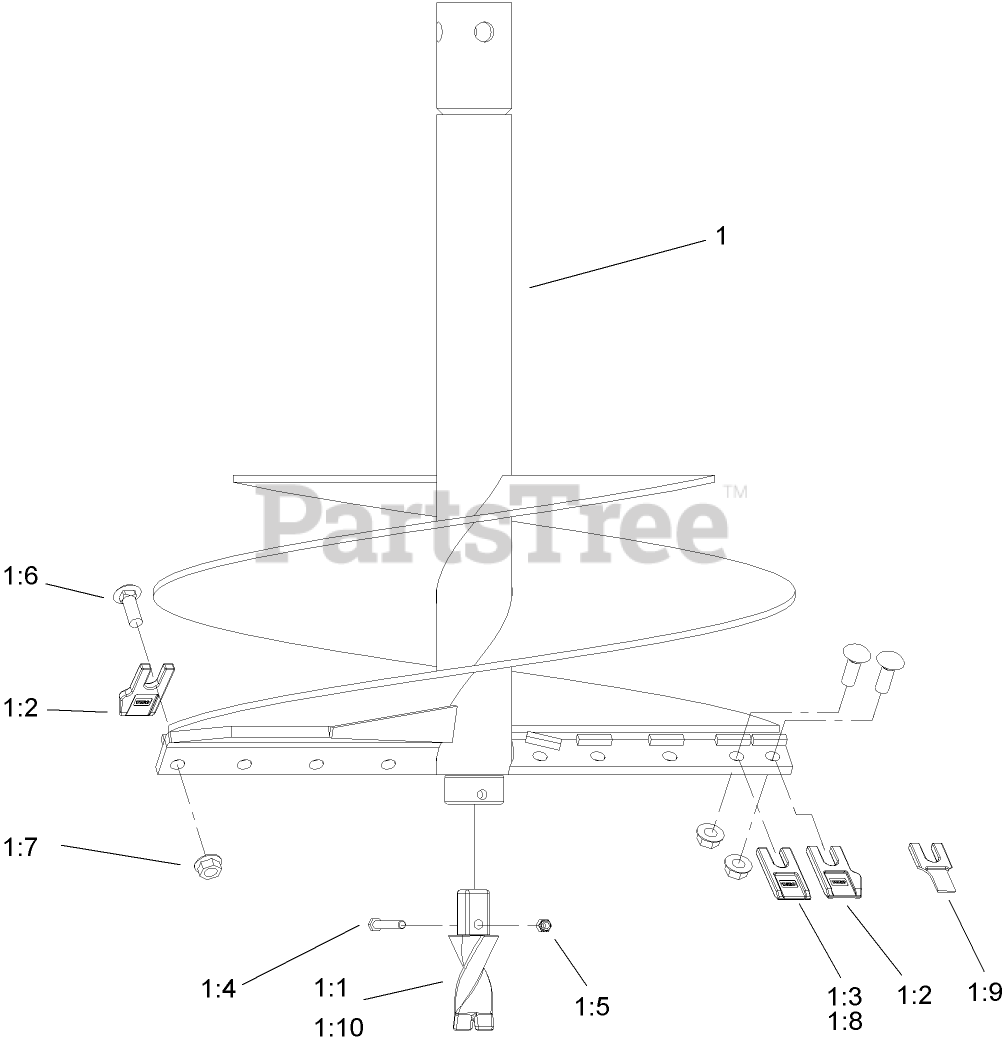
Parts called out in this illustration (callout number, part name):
1	AUGER-30 Inch
1:1	FISHTAIL-SHANK, SQUARE
1:2	TOOTH-AUGER, GAGE
1:3	TOOTH-AUGER, WISDOM
1:4	SCREW-HH
1:5	NUT-LOCK, NI
1:6	SCREW-CARR
1:7	NUT-LOCK, NI
1:8	TOOTH-WISDOM, CARBIDE
1:9	TOOTH-CHISEL, CARBIDE
1:10	PILOT-HARDFACED
